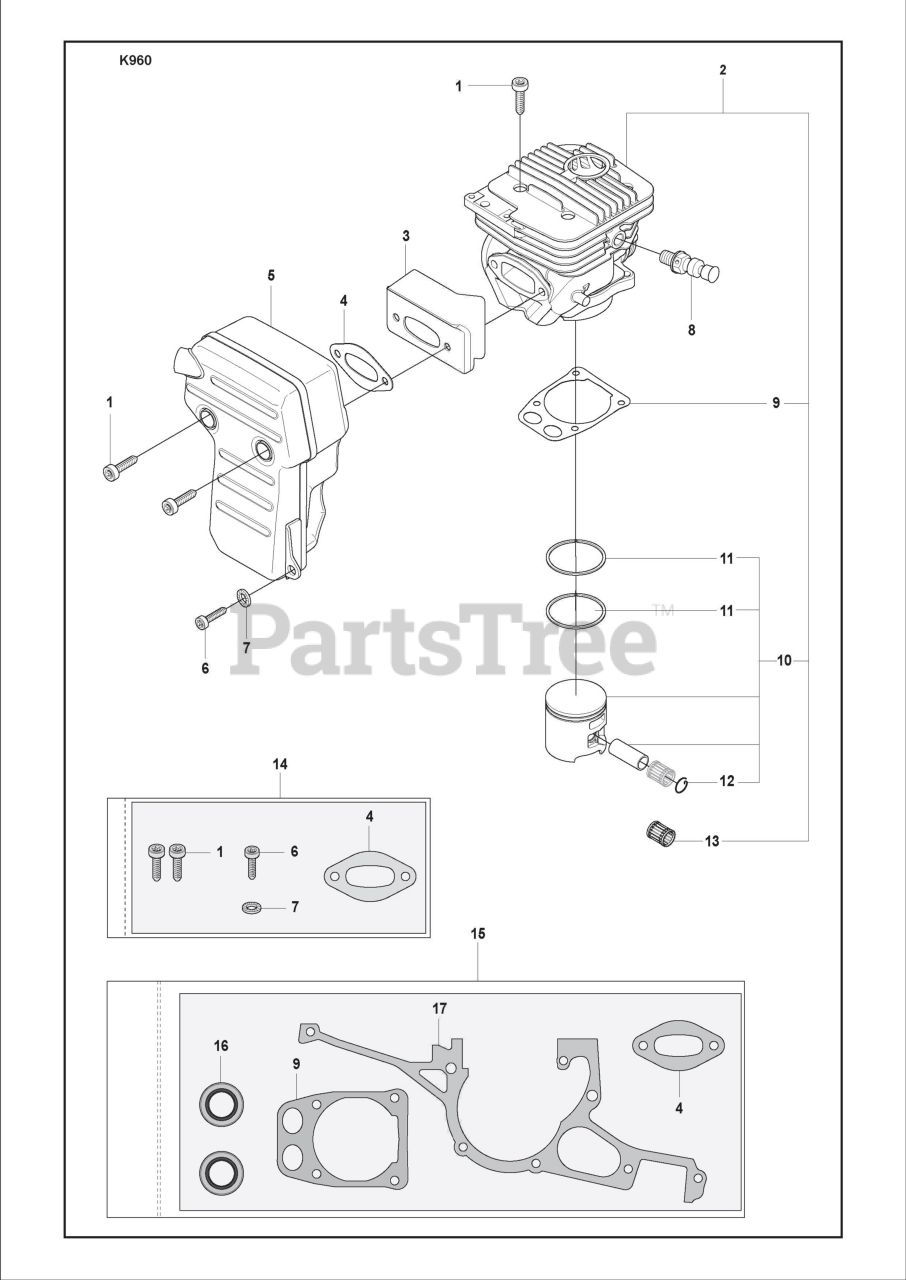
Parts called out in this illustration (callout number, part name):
2	Cylinder Assy
3	Heat Deflector
4	Gasket Muffler
5	Muffler
8	Decompression Valve
9	Gasket
10	Piston
11	Piston Ring
13	Needle Bearing
14	Muffler Mount Kit
15	Gasket Kit
16	Sealing Ring
17	Gasket
